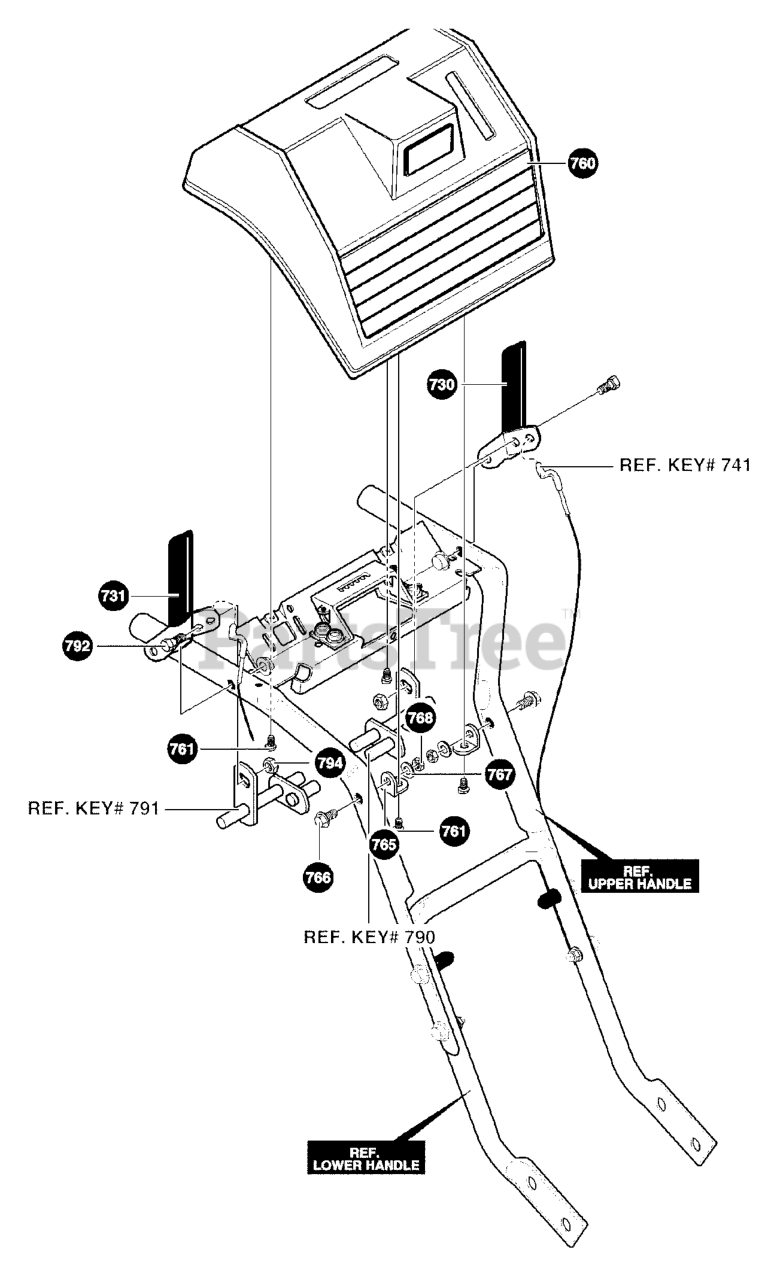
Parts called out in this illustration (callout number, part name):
730	CLUTCH HANDLE LH
731	CLUTCH HANDLE RH
761	SCREW, 10 X .62
765	BRACKET, PANEL
766	SCREW, 5/16-18 x 1.75
767	WASHER, HVSPTLK
768	NUT, 5/16-18
792	BOLT, 1/4-20 X .50
794	NUT, 1/4-20
